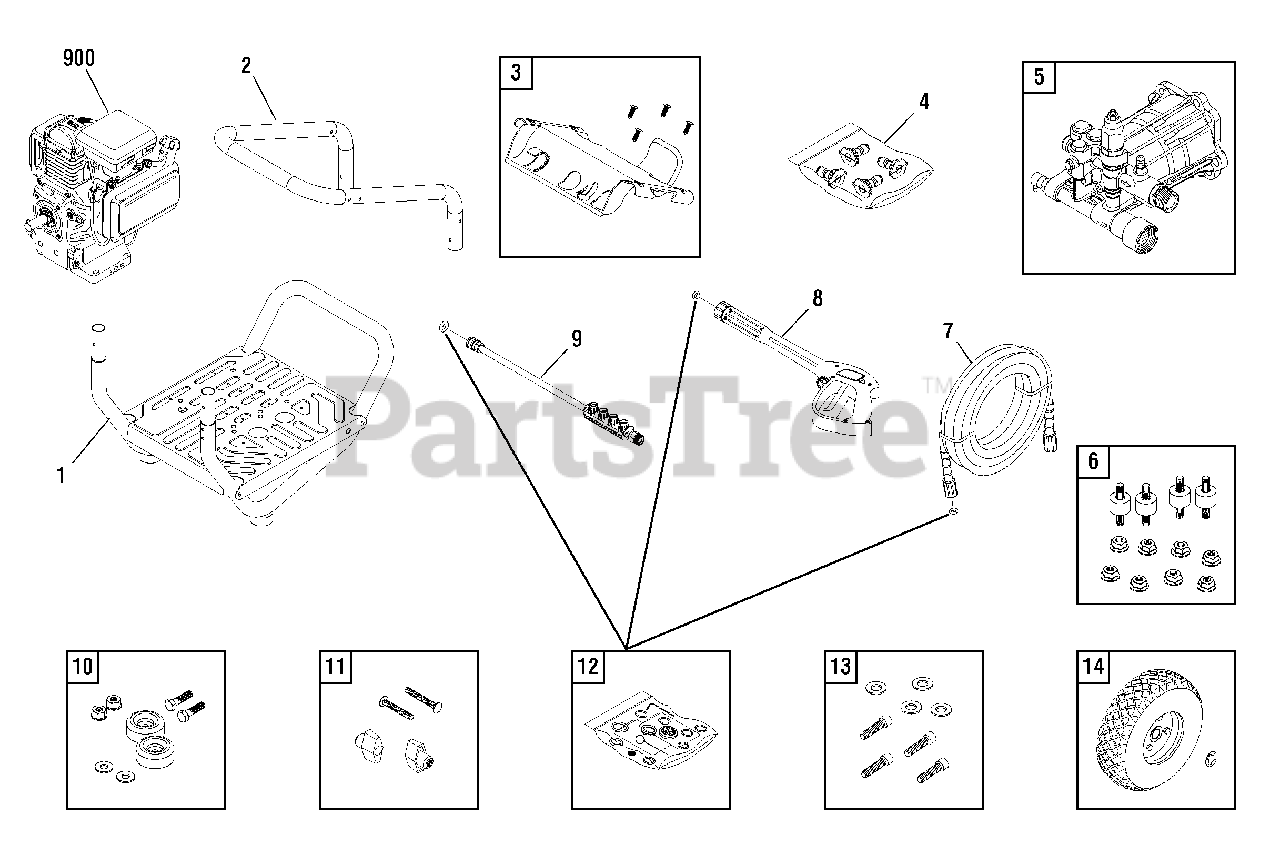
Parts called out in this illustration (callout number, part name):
4	KIT-QC NOZZLES
6	KIT-VIBRATION MOUNT
8	GUN
10	MOUNT-VIBRATION
11	KIT-HARDWARE HANDLE
13	KIT-HARDWARE PUMP MOUNTING
900	** ENGINE
